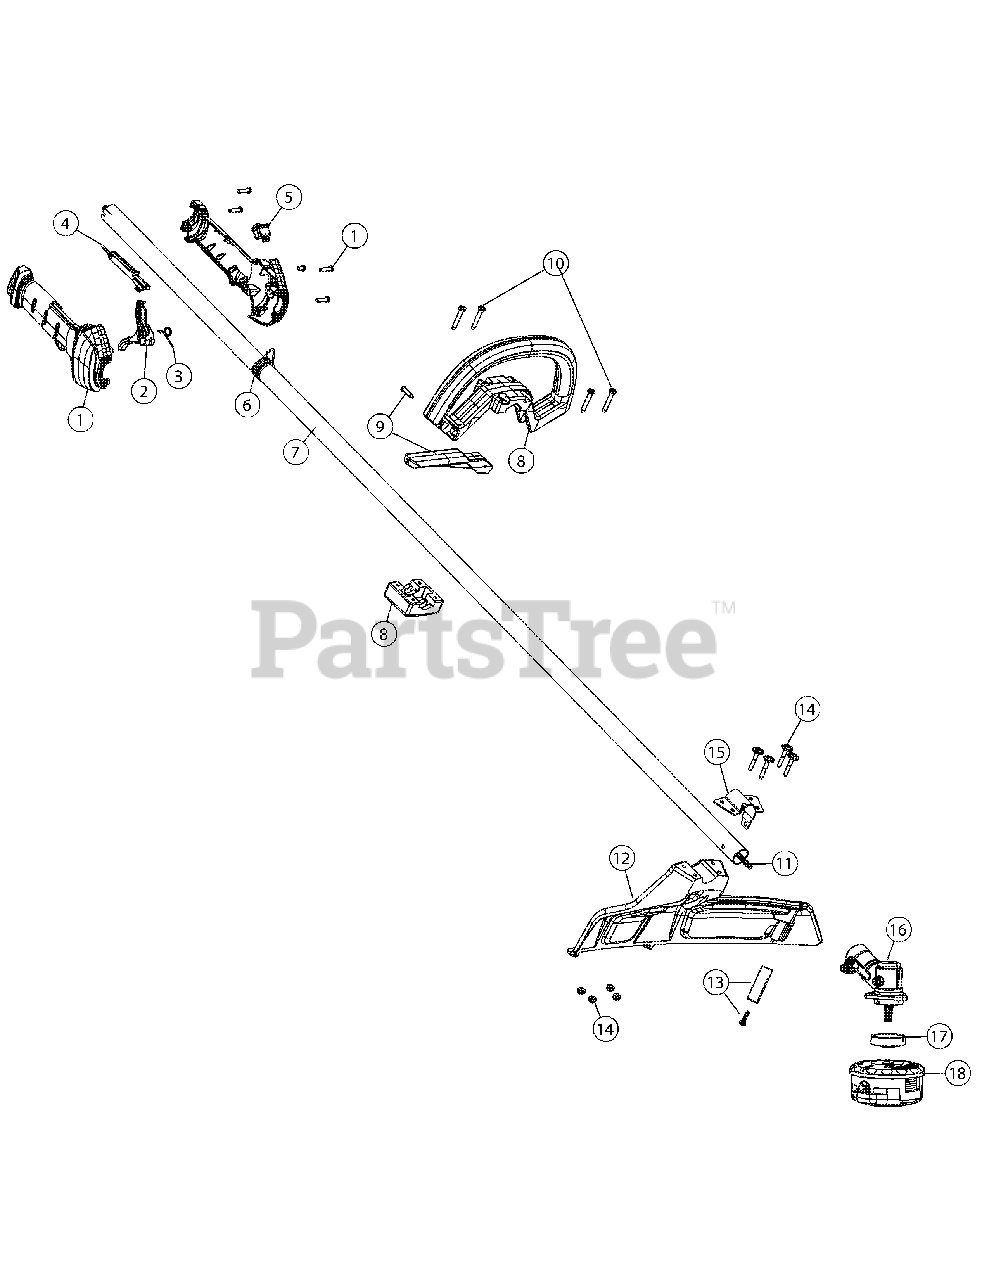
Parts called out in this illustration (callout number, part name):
1	Throttle Housing Assembly
2	Throttle Trigger
4	Throttle Lock-out
6	Shoulder Strap Clip
7	Driver Shaft Housing
8	D-Handle Assembly
9	Barrier Bar Assembly
11	Solid Drive Shaft
12	Shield Assembly
13	Blade Assembly
15	Guard Mounting Bracket
17	Gearbox Spacer
18	Cutting Head Assembly
